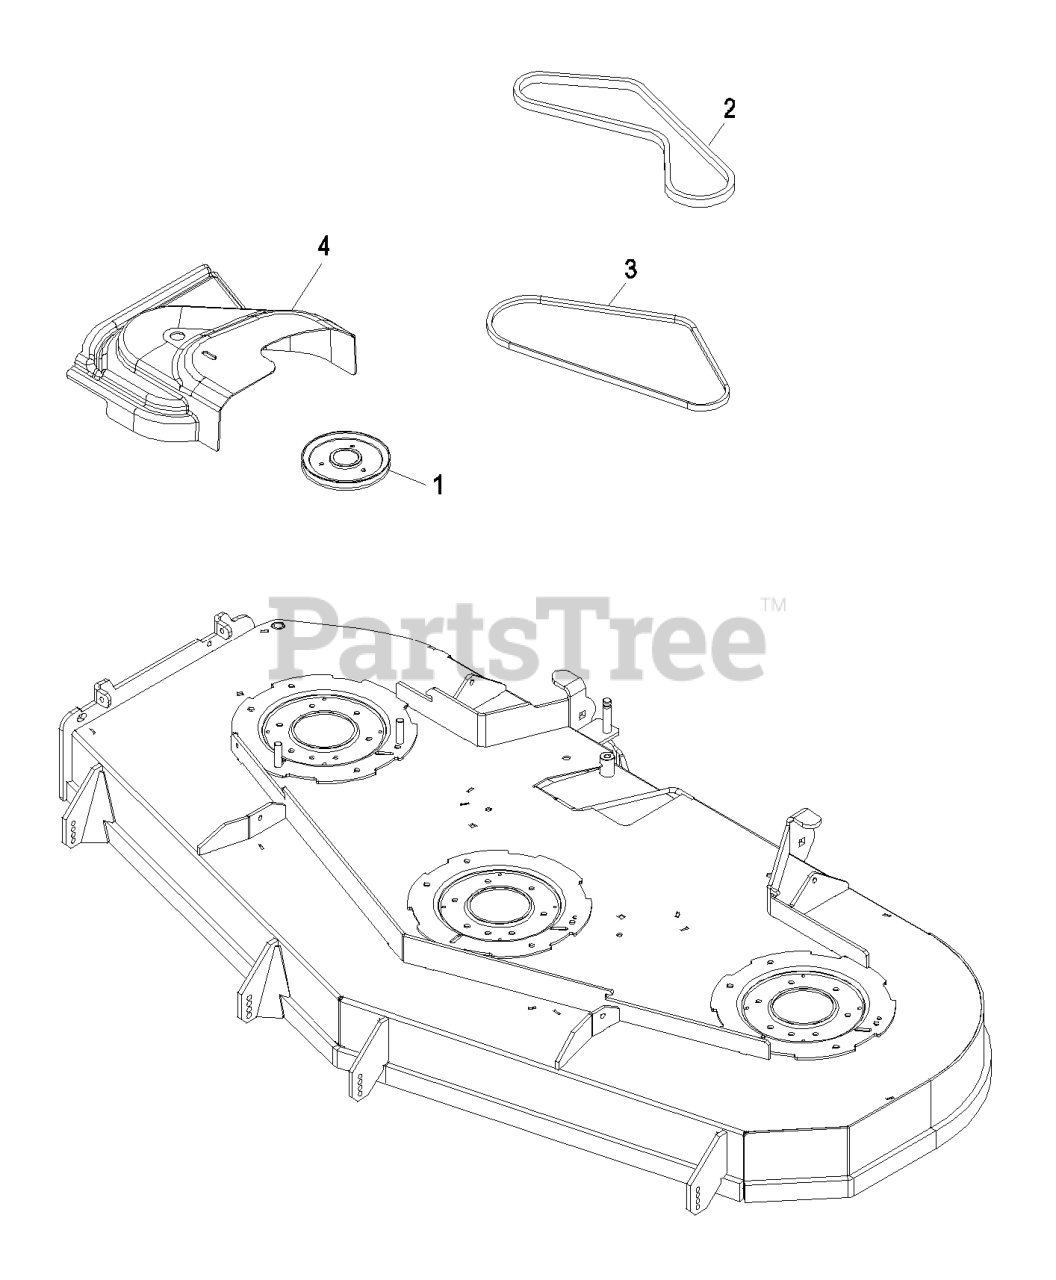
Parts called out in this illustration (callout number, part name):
2	BELT-BLOWER
3	BELT, BLOWER DRIVE 60
4	COVER,BELT UV 48
